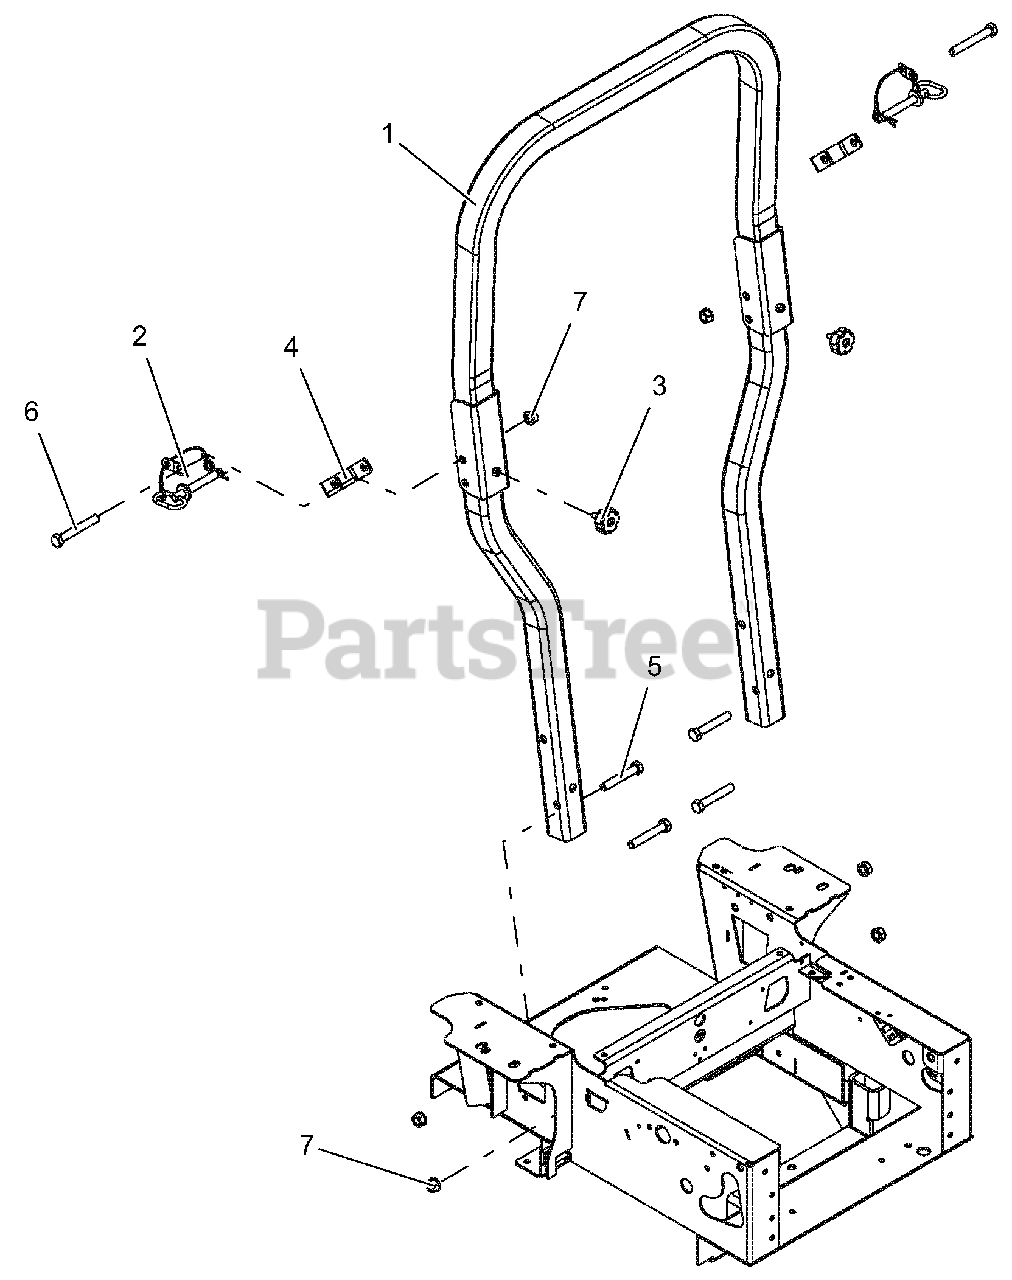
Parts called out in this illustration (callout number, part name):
1	ROPS, PT/PT100 REPLACEMENT
2	ASSY, ROPS PIN/LANYARD
3	KNOB, ROUND 5/16-18 X .750
4	BRKT, ROPS STOP, PRO-TURN YZ
5	BLT-HEX .50-13X3.00 GR5 YWZC
6	BLT-HEX .50-13X3.50 GR5 YWZC
7	NUT, LK-TOP-FLG .50-13 YWZC
